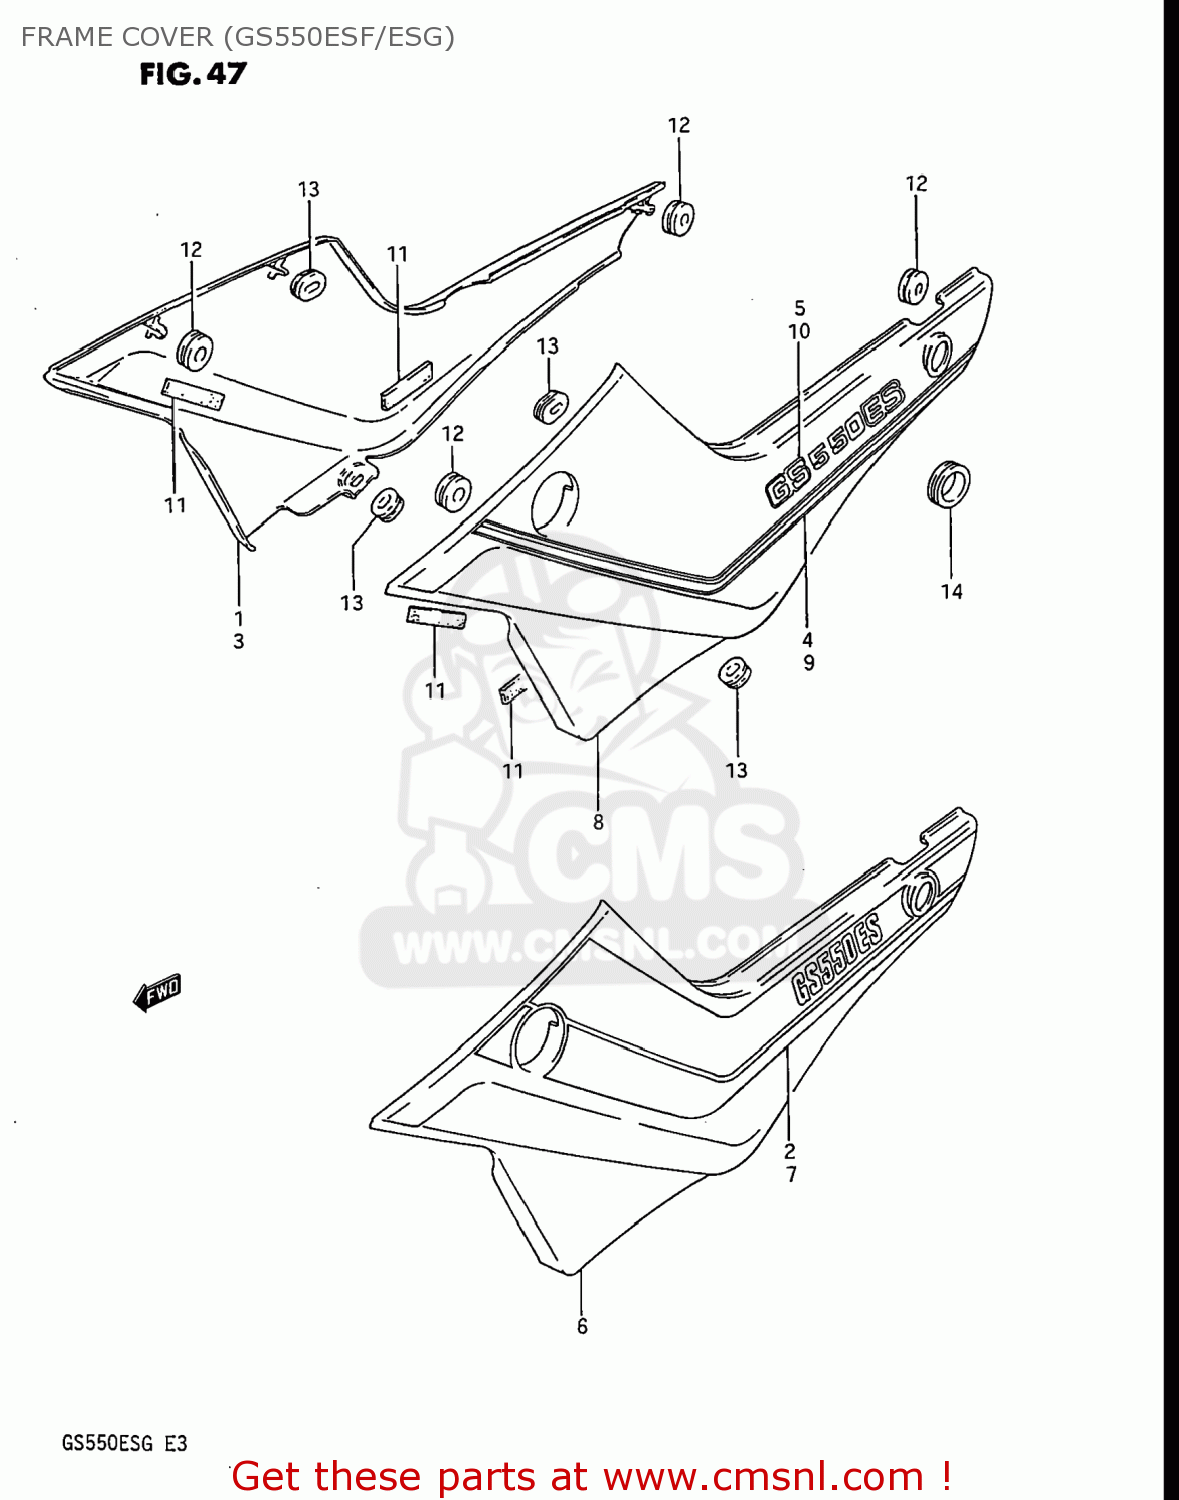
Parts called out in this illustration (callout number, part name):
1	COVER,FRAME,RIGHT
2	TAPE SET,FRAME COVER
3	COVER COMP,AIR CLEANER,LEFT
4	TAPE SET,FRAME COVER RH
5	EMBLEM
6	COVER,FRAME,LEFT
7	TAPE SET,FRAME COVER
8	COVER,FRAME,L
9	TAPE SET,FRAME COVER,LEFT
10	EMBLEM
11	RUBBER,FRAME COVER
12	CUSHION
13	CUSHION
14	GROMMET,SEAT LOCK HOLE
